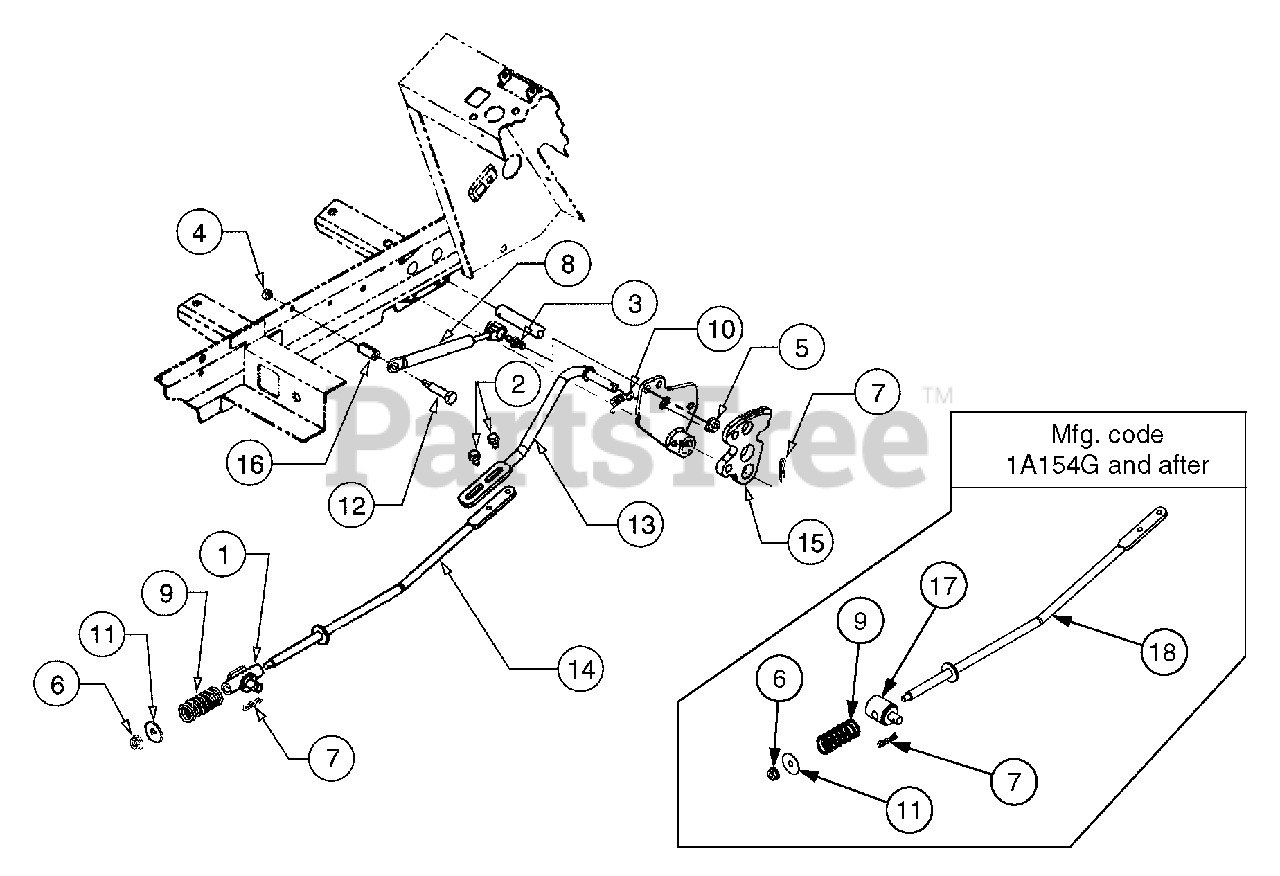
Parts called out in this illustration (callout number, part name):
1	Pivot Assembly
2	Screw, Hex Wsh Hd Tapp, 1/4-20 x .5
3	Screw, Ball, 5/16-18 x.56
4	Nut, Hex Sems, 1/4-20
5	Nut, Hex Flange Lock, 5/16-18 GR5
6	Nut, Hex Flange Lock, 1/4-20
7	Pin, Internal Cotter
8	Cylinder, Damper
9	Spring, Compression, .63 ID x 2
10	Spring, Extension, 3/8 OD x 1.44
11	Washer, Flat, .265 x 1 x .030
12	Bolt, Shoulder, .374 Dia x 1.375
13	Rod, Front Control
14	Rod, Rear Hydro Control
15	Plate, Cruise
16	Spacer, Split Tubing, .375 ID x 1.04
18	Rod, F/R Control
